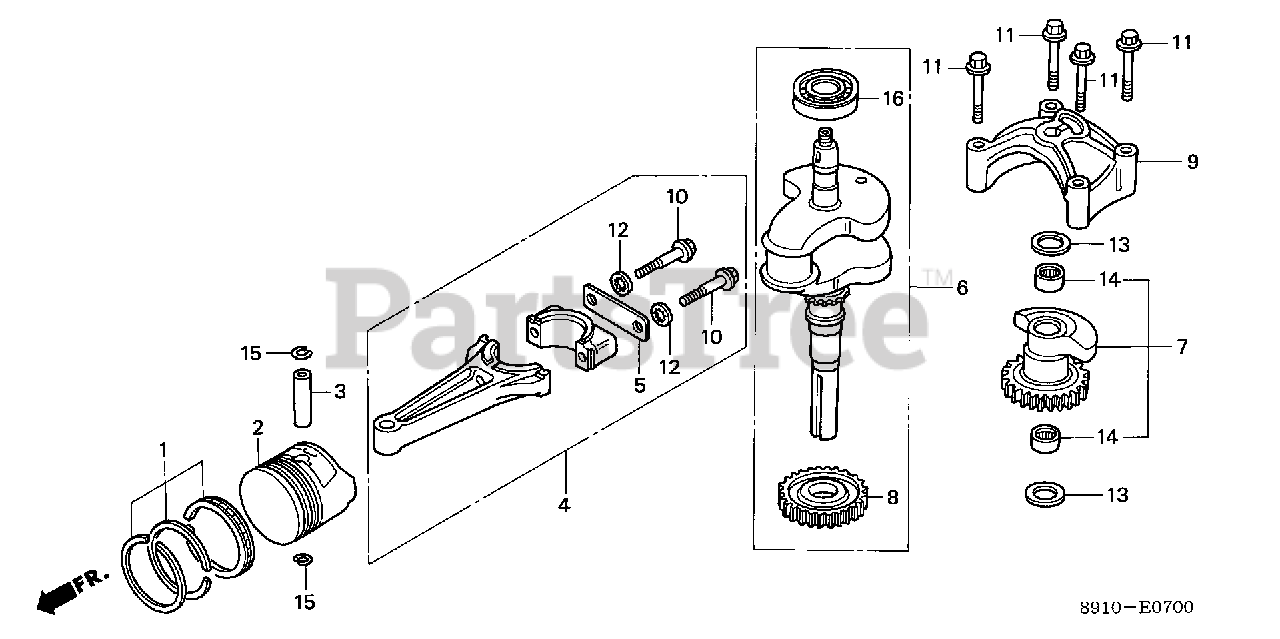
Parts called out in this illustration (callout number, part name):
1	RING SET, PISTON (STD)
1	RING SET, PISTON (STD) (NOT AVAILABLE)
1	RING SET, PISTON (OVER SIZE)
1	RING SET, PISTON (0.25)
1	RING, PISTON (OVER SIZE)
1	RING SET, PISTON (0.50)
1	RING SET, PISTON (0.75)
2	PISTON (STD)
2	PISTON (0.25)
2	PISTON (0.50)
2	PISTON (0.75)
3	PIN, PISTON
4	ROD ASSY., CONNECTING
5	WASHER, CONNECTING ROD
6	CRANKSHAFT
7	WEIGHT, BALANCER
8	GEAR, BALANCER (38T)
9	COVER, BALANCER
10	BOLT, CONNECTING ROD (8MM)
10	BOLT, CONNECTING ROD (8MM) (NOT AVAILABLE)
11	BOLT, FLANGE (6X50)
12	WASHER, LOCK (8MM)
13	WASHER, THRUST (15MM)
14	BEARING, NEEDLE
15	CLIP, PISTON PIN (19MM)
16	BEARING, RADIAL BALL (6206)
